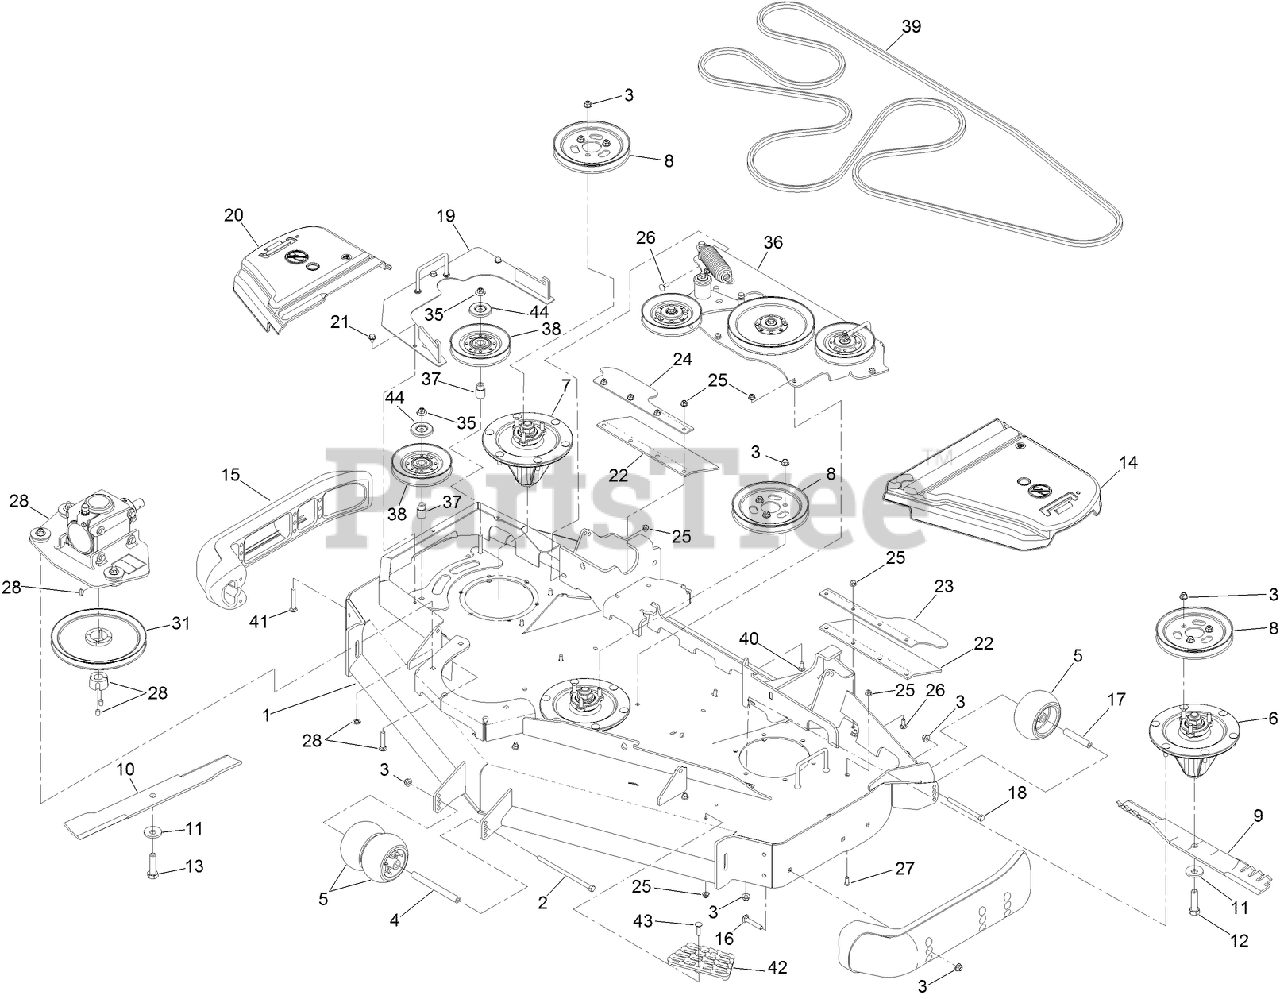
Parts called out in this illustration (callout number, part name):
1	DECK DECAL ASM
2	SCREW-HH
3	NUT-HF, NI
4	SPACER-WHEEL
5	ROLLER-SCALP, ANTI
6	SPINDLE ASM
7	LH SPINDLE ASM
8	PULLEY
9	BLADE-ATOMIC, 20.5IN
10	BLADE-ROTARY, 20.5IN LOW FLOW
11	WASHER-BLADE BOLT, HEAVY
12	SCREW-BLADE
13	SCREW-BLADE, LH
14	COVER-BELT, LH
15	SKID-BUMPER, DECK
16	SCREW-HH
17	TUBE-SPANNER
18	SCREW-HH
19	COVER-DRIVE REVERSE
20	COVER-BELT, RH
21	SCREW
22	GUARD-TIRE
23	SUPPORT-FLAP, OUTER (LH)
24	SUPPORT-FLAP, OUTER (RH)
25	NUT-HF, NI
26	SCREW-CARR
27	SCREW-HSBH
28	GEARBOX ASM
31	PULLEY
35	NUT-FLANGE, NI
36	IDLER MOUNT ASM
37	STANDOFF-IDLER
38	IDLER V
39	BELT-BB
40	SCREW-CARR
41	SCREW-CARR
42	STEP-DECK
43	SCREW-CARR
44	SHIELD-DUST
